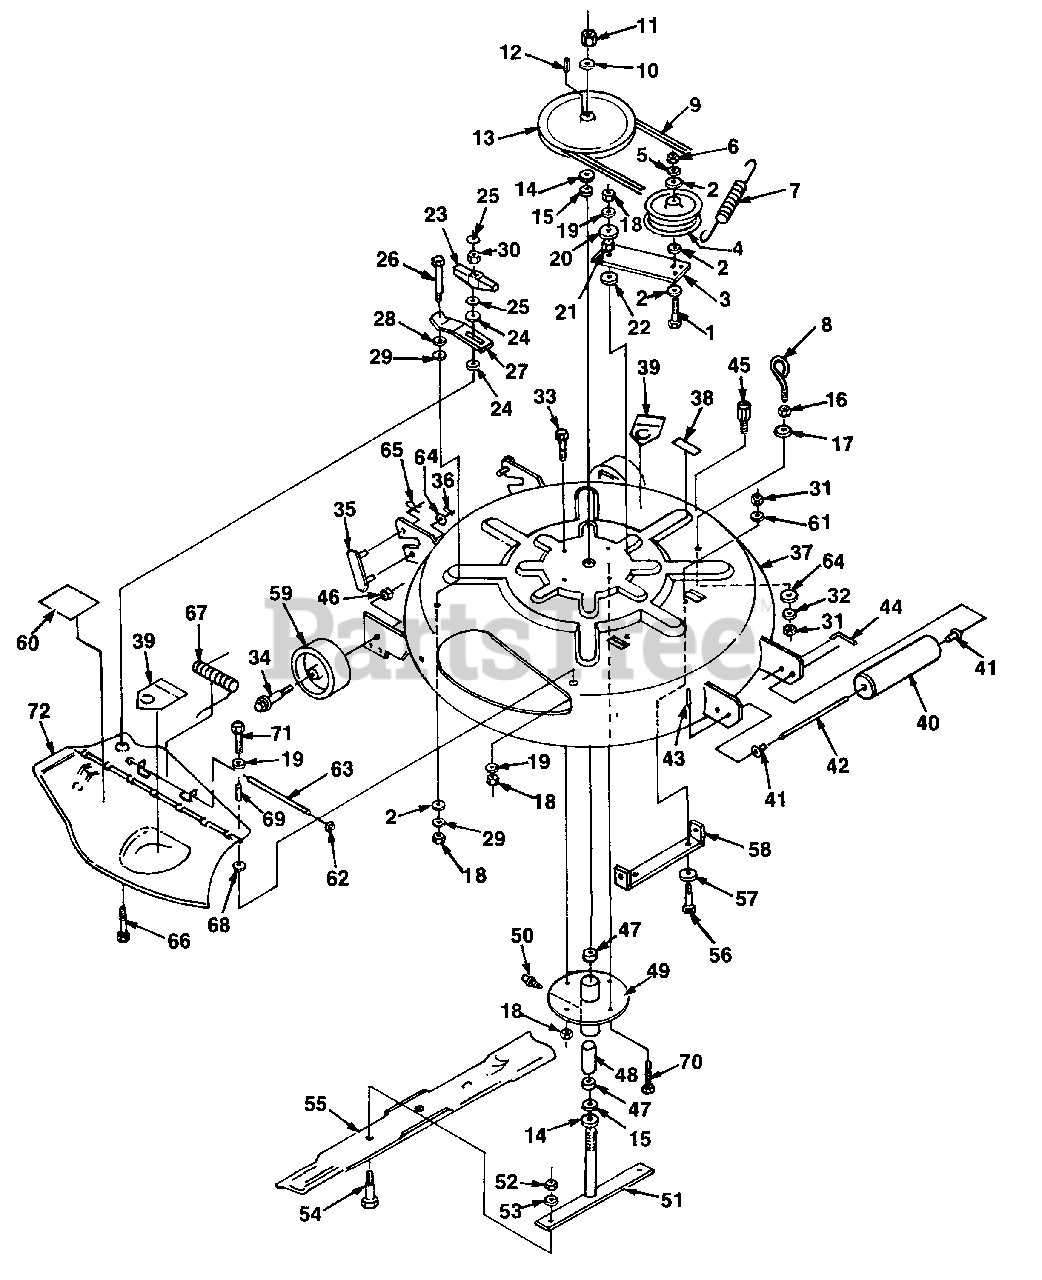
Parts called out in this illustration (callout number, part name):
2	WASHER- Flat 3/8
3	ARM- Pivot
4	PULLEY- Idler
5	WASHER- Lock 3/8
6	NUT- Hex centerlock 3/8 x 16
10	WASHER- Flat 3/4
11	NUT- Hex locking
13	PULLEY- Spindle
15	WASHER- Flat
16	NUT- Hex 1/4-20
17	WASHER- Flat 1/4"
18	NUT- Hex centerlock
19	WASHER- Lock 5/16
20	WASHER- 1 3/4 x .144/.1
21	SPACER- Idler arm
22	WASHER- Idler arm
23	KNOB- Handle
24	WASHER
25	NUT- Push
26	BOLT- Shoulder
27	ARM- Pivot
28	WASHER- Spring
29	WASHER- Flat
30	NUT- 1/4-20
31	NUT- Hex centerlock
32	WASHER- Lock 1/4
33	SCREW- Cap hex hd 5/16-18 x 3/4
34	BOLT- Wheel
35	STOP LINK ASSY.
36	PIN- Cotter
37	DECK-
38	DECAL- No Step
39	WARNING LABEL- CPSC
41	BUSHING- Roller
42	SHAFT- Roller
43	PIN- Roll 3/16-13/16
44	PIN- Hold
45	PLUG- Wash out
46	NUT- Hex centerlock 3/8-16
47	BEARING- Cutter shaft
48	SPACER- Bearing
49	SPINDLE HOUSING
50	FITTING- Lubricant
51	SPINDLE & ADAPTER
52	NUT- Hex centerlock
53	WASHER- Lock 1/2
54	SCREW- Cap hex hd. 1/2-13 x 1.25
55	BLADE- 35"
56	SCREW- Cap hex hd.
57	WASHER- 5/16
58	BRACKET- Front lift
60	DECAL- Door
61	WASHER- Lock
63	ROD- Deck hinge
64	WASHER- Flat 1/4"
65	PIN- Hair
66	SCREW-1/4 x 1 1/4
67	SPRING- Torsion
68	WASHER- Flat
70	SCREW- 3/8-16 x 2.25
71	SCREW- 5/16-18 x 5/8
72	PLATE & COVER ASSY.
